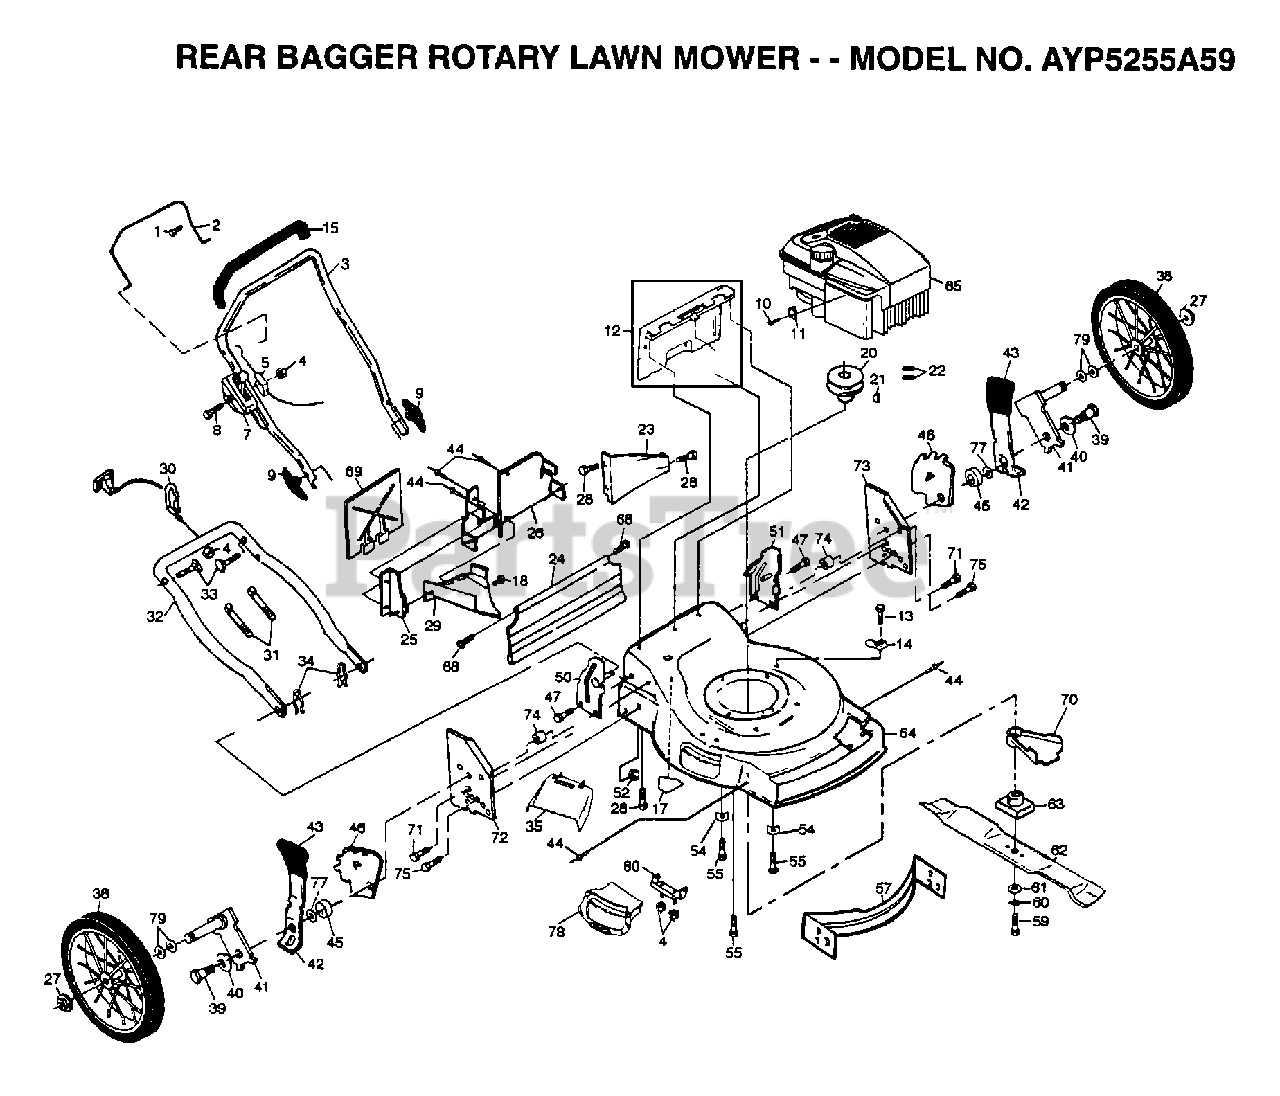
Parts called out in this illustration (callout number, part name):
1	"SCREW,PAN HD"
2	"BAR,CONT"
5	"CABLE,ENG ZONE CO"
7	"CONTROL, THROTTLE"
8	SCREW.HXHD.WASH.
9	KNOB PM
10	SCREW PM
11	CABLE CLAMP
12	KIT.DOOR.REAR.22
13	TAPPING SCREW
14	GUIDE CLIP PM
17	DECAL-DANGER PM
18	SCREW PM
20	ENGINE.PULLEY.FWG
21	HI PRO KEY PM
22	SCREW
23	REAR BAFFLE
24	SKIRT.REAR.FGD.22
26	PLATE.BACK
27	HEX FLANGE LOCKNT
28	SCREW
29	DISCHARGE BAFFLE
30	ROPER GUIDE PM
33	BOLT.HANDLE.LM
34	HAIRPIN COTTER
35	GUARD.DISCH.CLIPO
37	WASHER
38	ASM WHL & TIRE
39	BOLT SHLD 3/8-16
41	AXLE ARM ASSY R
42	SPRING SELECTOR
43	KNOB PM
44	BLIND RIVET
46	BRACKET.ADJ.9POS.
47	SCREW
52	LOCKNUT PM
55	SCREW
59	SCREW
60	LOCKWASHER
61	"WASHER,HARDEN"
62	"BLADE.MULCH.22"""
63	ADAPTOR.BLADE.LM
64	KIT.HSG.22PT.FWGD
68	HINGE SCREW
69	MULCHER PLATE
72	WHL.BRKT.SUPT. RH
73	WHL BRKT SUPT LH
77	WASHER PM
78	KIT.DOOR.MUL.CO
79	WAVE WASHER
80	BRACKET.HINGE.W/F
